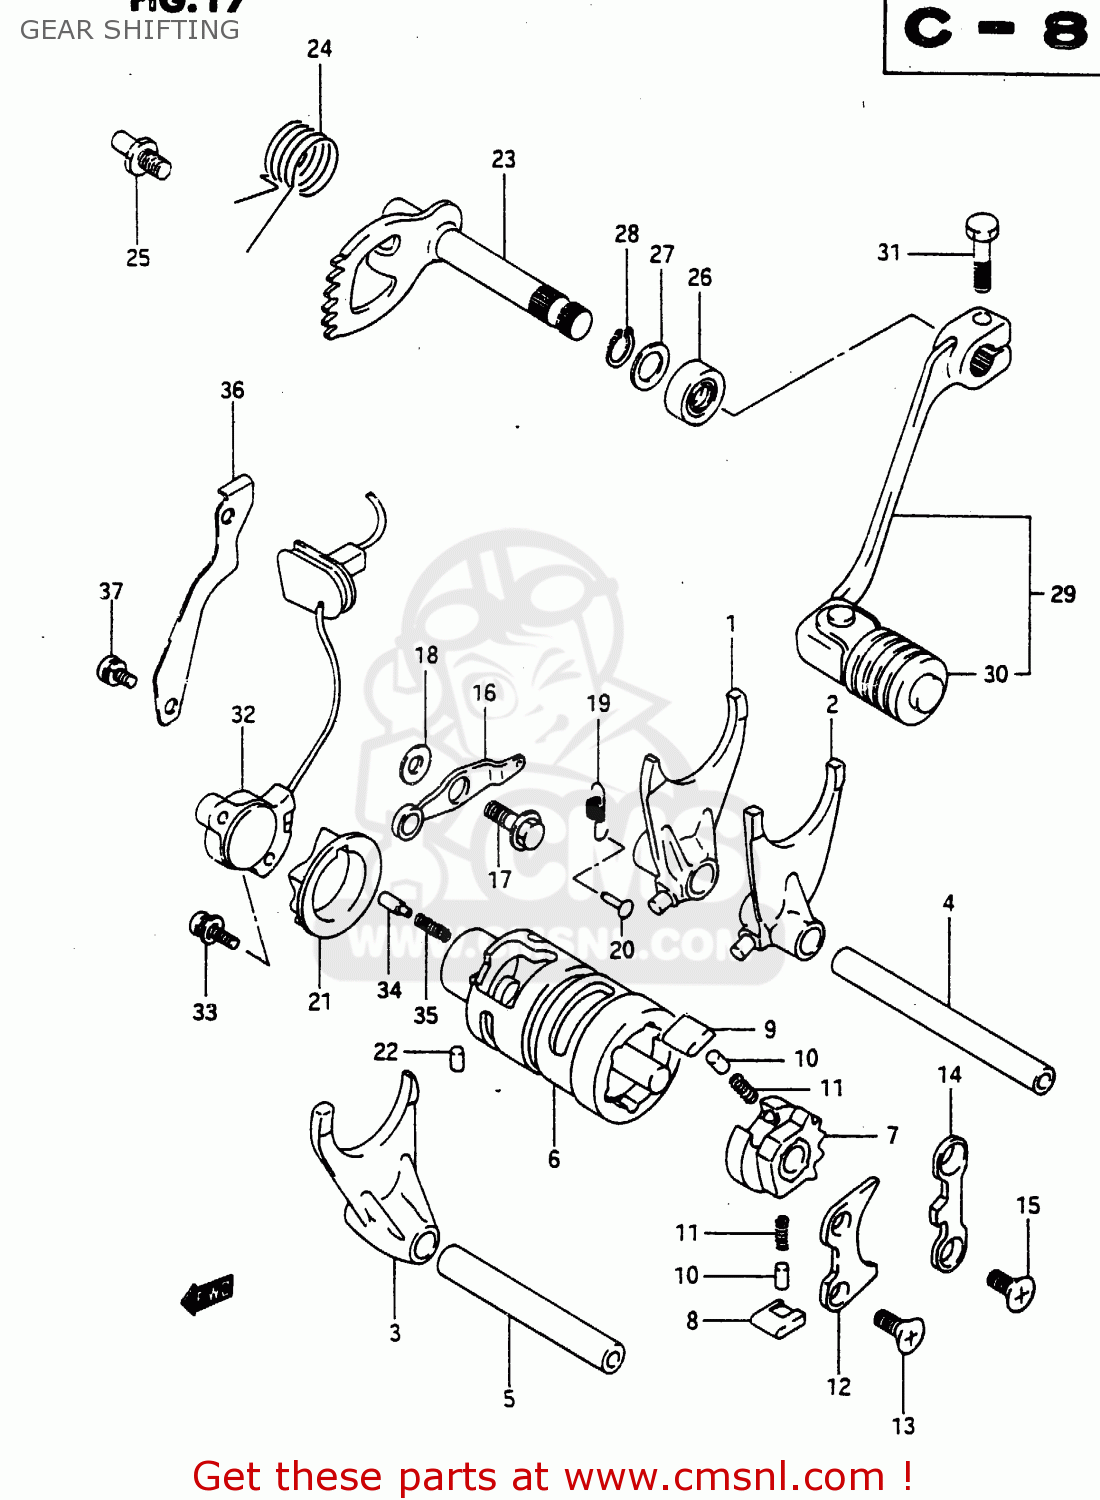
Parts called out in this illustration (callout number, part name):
1	FORK,GEAR SHIFT NO.1
2	FORK,GEAR SHIFT NO.2
3	FORK,GEAR SHIFT NO.3
4	SHAFT,GEAR SHIFT FORK
5	SHAFT,GEAR SHIFT FORK
6	CAM,GEAR SHIFT
7	GEAR,GEARSHIFT CAM DRIVE
8	PAWL,GEAR SHIFT NO.1
9	PAWL,GEAR SHIFT NO.2
10	PIN(5X8)
11	SPRING
12	LIFTER,GEAR SHAFT PAWL
13	SCREW
14	STOPPER,GEAR SHIFT POLE
15	SCREW
16	STOPPER,GEAR SHIFT CAM
17	BOLT
18	WASHER
19	SPRING
20	RIVET
21	PLATE,SHIFT CAM STOPPER
22	PIN 4X6
23	SHAFT,GEAR SHIFT
24	SPRING
25	STOPPER,GEAR SHIFT CAM
26	OIL SEAL
27	WASHER
28	CIRCLIP
29	LEVER ASSY,GEAR SHIFT
30	RUBBER,GEAR SHIFT PEDAL
31	BOLT
32	BASE ASSY,NEUTRAL SW TERMINAL
33	SCREW
34	PIN(5X15.5)
35	SPRING
36	CLAMP,LEAD WIRE
37	SCREW
